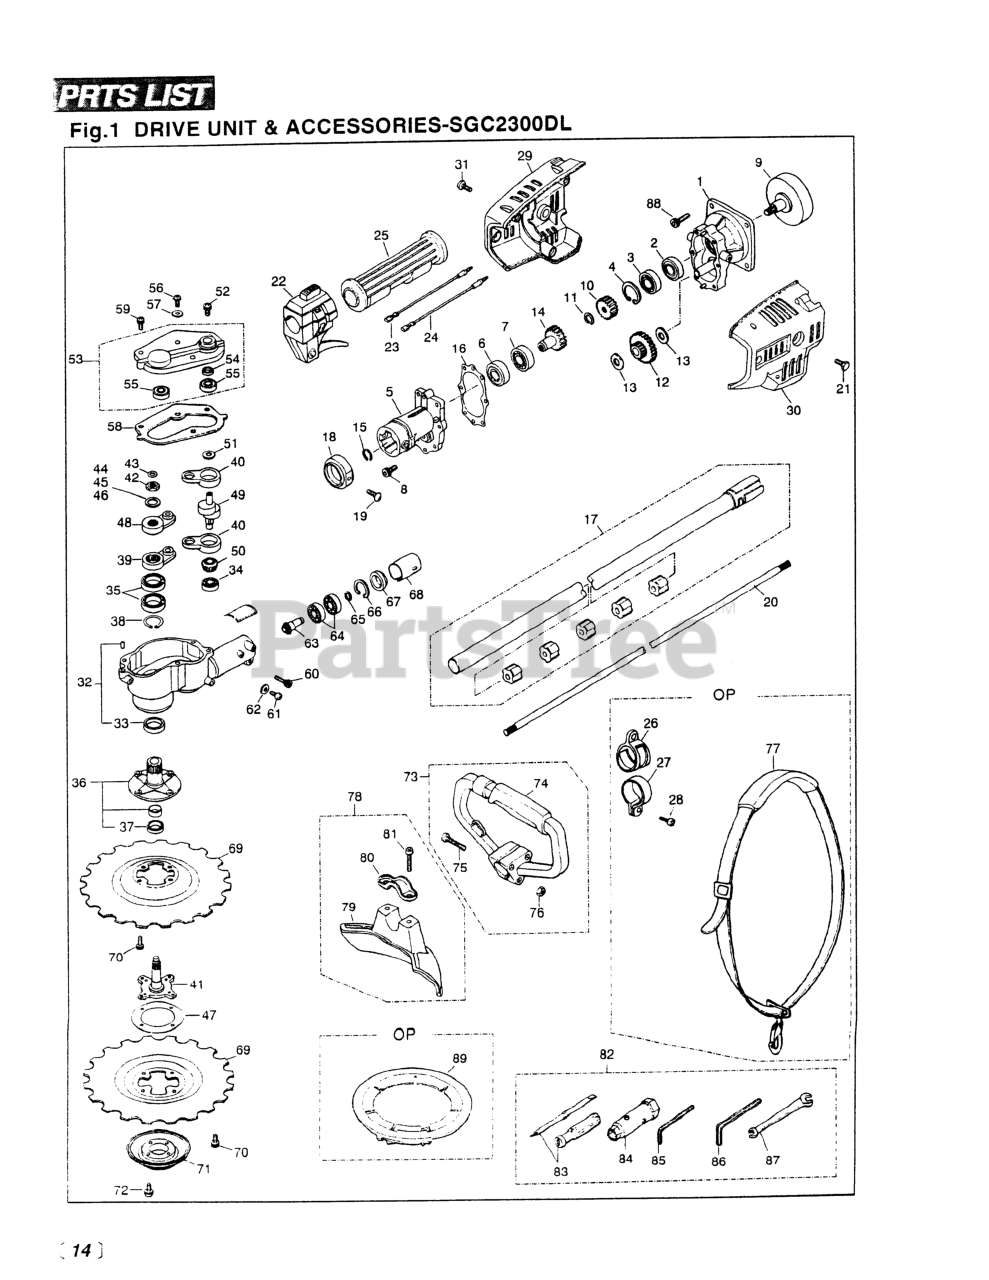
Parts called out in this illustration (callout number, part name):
2	BEARING
3	BEARING
4	RING, SNAP, M28 x 1.2
5	CASE, FRONT
6	BEARING
7	BEARING
8	BOLT, M5 X 20
9	DRUM
10	GEAR, PINION
11	RING, SNAP
12	GEAR (RPLS 3805-11330)
13	WASHER
14	GEAR, WHEEL
18	CAP
19	SCREW, M5 X 10
20	SHAFT
21	BOLT, M6 x 8
23	CORD-A, BLACK
24	CORD-B, RED
26	HANGER (REPLACES -18100)
28	SCREW, M5X20 (RPLS.1400-75510)
29	COVER, RIGHT (RPLS. -11510)
30	COVER, LEFT (RPLS -11520)
32	CASE, CUTTER (RPLS -13100)
33	SEAL, OIL
35	BEARING
36	SHAFT, OUTER-C
37	SEAL, OIL
38	RING, SNAP, M20 x 1.2
39	ARM, LOWER (RPLS -13411)
41	SHAFT, INNER
44	SHIM, 0.3t
45	SHIM, 0.2T
46	SHIM, 0.1t
48	ARM, UPPER (RPLS -13611)
49	CRANKSHAFT (RPLS -13710)
50	GEAR
51	WASHER, M8 x 1.2
52	BOLT
53	COVER
54	SEAL, OIL
55	BEARING (RPLS. T4001-31340)
56	SCREW, M6 x 10
57	GASKET
58	GASKET
59	BOLT, M5 x 20
61	SCREW, M5 x 14
63	PINION
64	BEARING (RPLS T3403-13510)
65	RING, SNAP
66	RING, SNAP, M26 X 1.2
67	PACKING
68	SPACER (RPLS -13950)
70	BOLT, M6 x 8
71	STABILIZER (RPLS -15151)
72	SCREW, M5 X 8
74	HANDLE (RPLS -14310)
75	SCREW, M5 x 30(RPLS 0263-00530
76	NUT, M5 X 4
78	GUARD ASSY (RPLS -24000)
79	GUARD (RPLS -24110)
80	CLAMP (REPLACES 5807-24120)
81	BOLT, M6 x 1.30
82	TOOL SET
83	SCREWDRIVER
85	WRENCH (TOOL)
86	WRENCH (TOOL)
87	SPANNER, 8 X 10 (RPLS 2540- )
89	COVER (REPLACES D0041) ACC.
